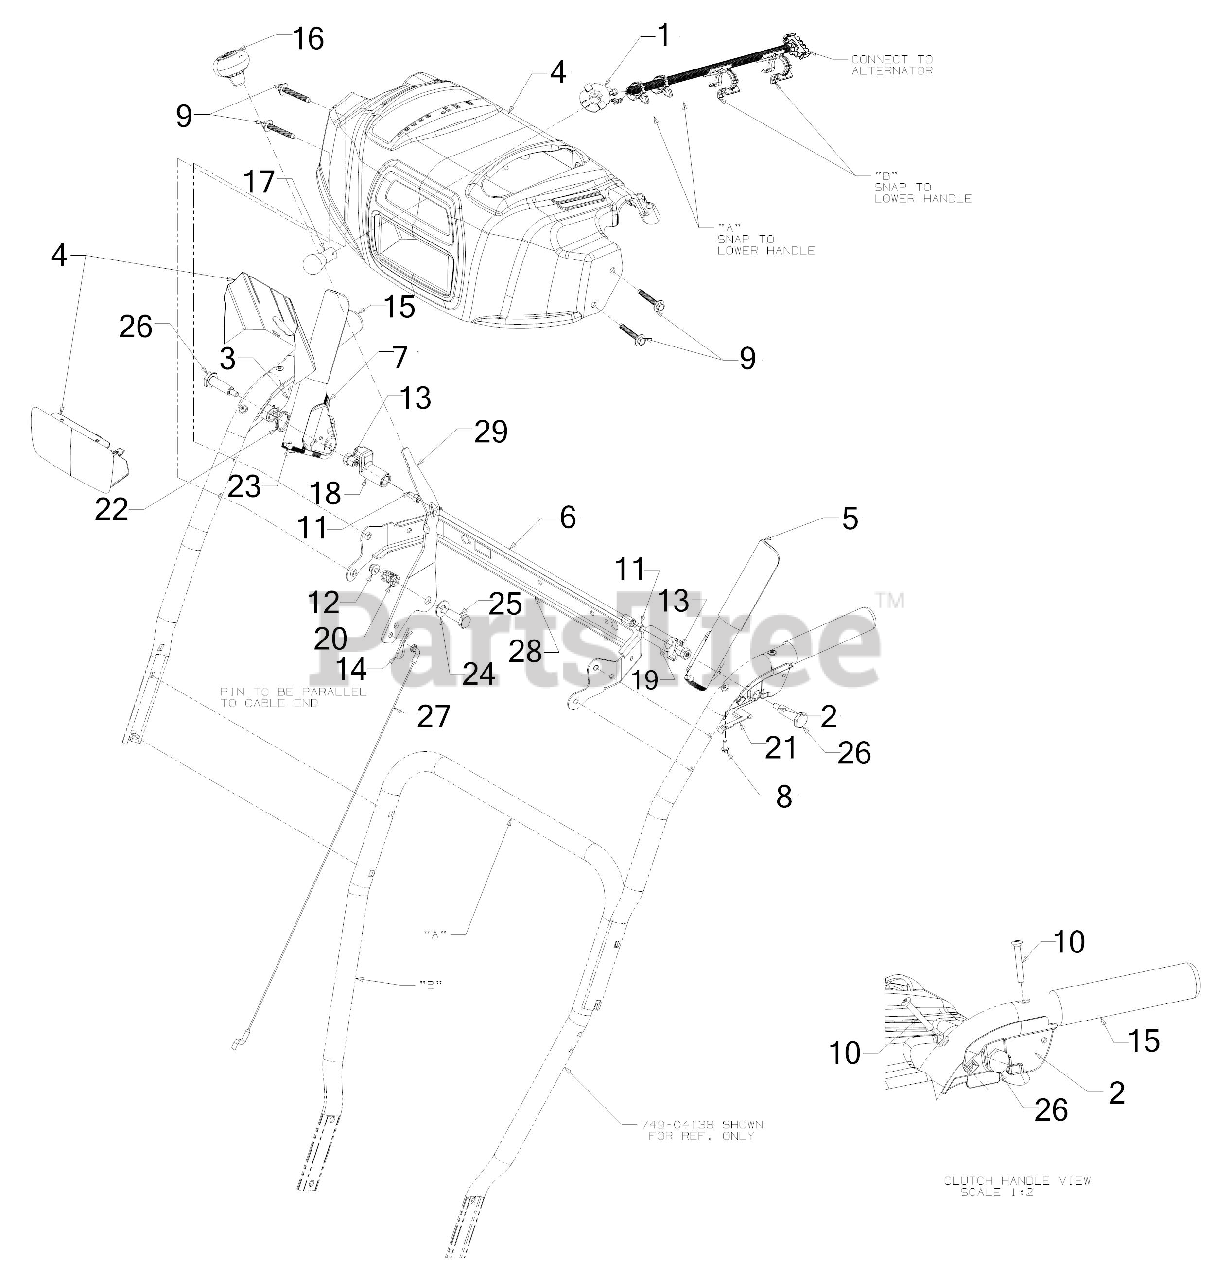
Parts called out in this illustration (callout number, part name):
1	HEADLIGHT SOCKET
2	CLUTCH LOCK HANLE ASSEMBLY (LH)
3	CLUTCH LOCK HANLE ASSEMBLY (RH)
4	HANDLE PANEL ASSEMBLY (CRAFTSMAN)
5	HANDLE ASSEMBLY (LH)
7	HANDLE ASSEMBLY (RH)
8	SCREW #8-16 x .50
9	SCREW 1/4-20 x 1.625
10	SCREW #10-24 x 1.375
11	SCREW 1/4-20 x .50
12	FLANGE LOCK NUT
13	HEX NUT W/PATCH
14	INTERNAL COTTER PIN
16	SHIFT KNOB
19	CLUTCH LOCK CAM
20	COMPRESSION SPRING
21	CLUTCH SPRING
22	TORSION SPRING
23	RUBBER BUMPER
24	FLAT WASHER
25	SHOULDER SCREW
26	SHOULDER SCREW .437 x 1.345 1/4-20
27	SPEED SELECTOR CABLE (PLASTIC)
